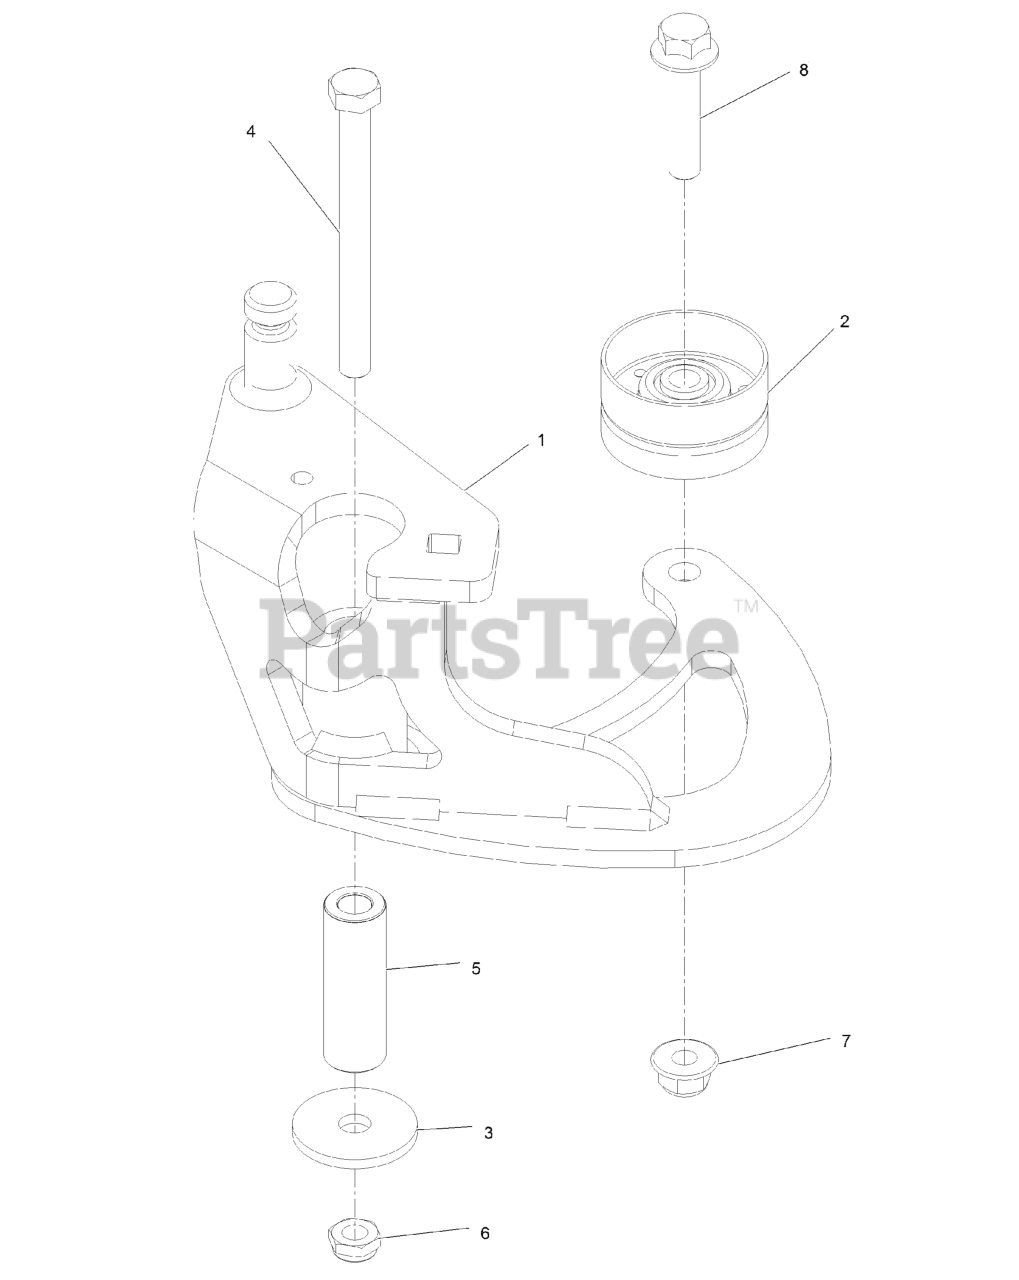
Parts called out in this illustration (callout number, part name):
1	ASM, IDLER ARM W/ BUSHINGS
2	IDLER, FLAT
4	SCREW-HH
5	TUBE, IDLER PIVOT
7	NUT-HF, NI
8	SCREW-HHF
